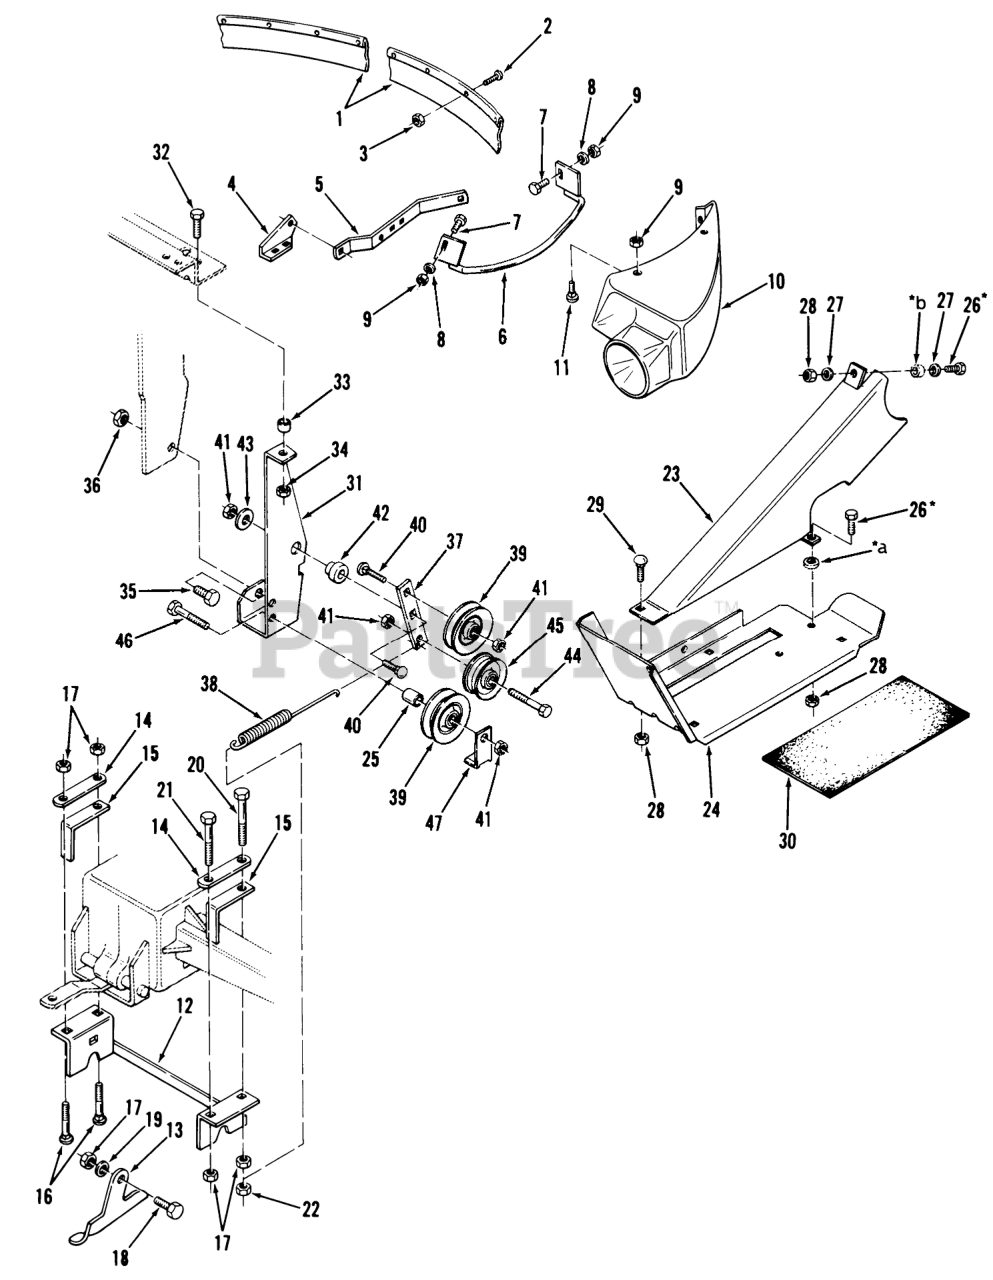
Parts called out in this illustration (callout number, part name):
1	ASSY COVER
2	Screw
3	#10-24 Kep-Nut
4	Deck Bracket-Mower
5	Draft Bar-Mower
6	Blade Guard Assembly
7	Bolt
8	WASHER 5/16 SAE
9	Nut
10	NOZZLE ASSY
11	Bolt Carnage
12	Bracket
13	PLATE-LATCHING
14	BRACKET-REAR LINK MOUNTING
15	SPACER-BRACKET
16	Bolt-Carriage
17	NUT
18	BOLT
19	Washer
20	Bolt 3/8-16 x 4
21	HHCS
22	NUT
23	Belt Guard
24	Footrest
25	SPACER
26	Bolt
27	WASHER 5/16 SAE
28	Nut
29	CARRIAGE BOLT -4
30	PAD-FOOTREST
31	Roller
32	Bolt
33	Spacer
34	Nut
35	Bolt
36	Eslok Nut
37	Idler Arm
38	SPRING-EXTENSION
39	PULLEY-IDLER STATION
40	Carriage Bolt 3/8-16 x 1 1/2 Short Neck
41	Nut
42	SPACER-CLUTCH LINK
43	WASHER
44	Bolt
45	IDLER PULLEY
46	Bolt
47	BRACKET GUARD
